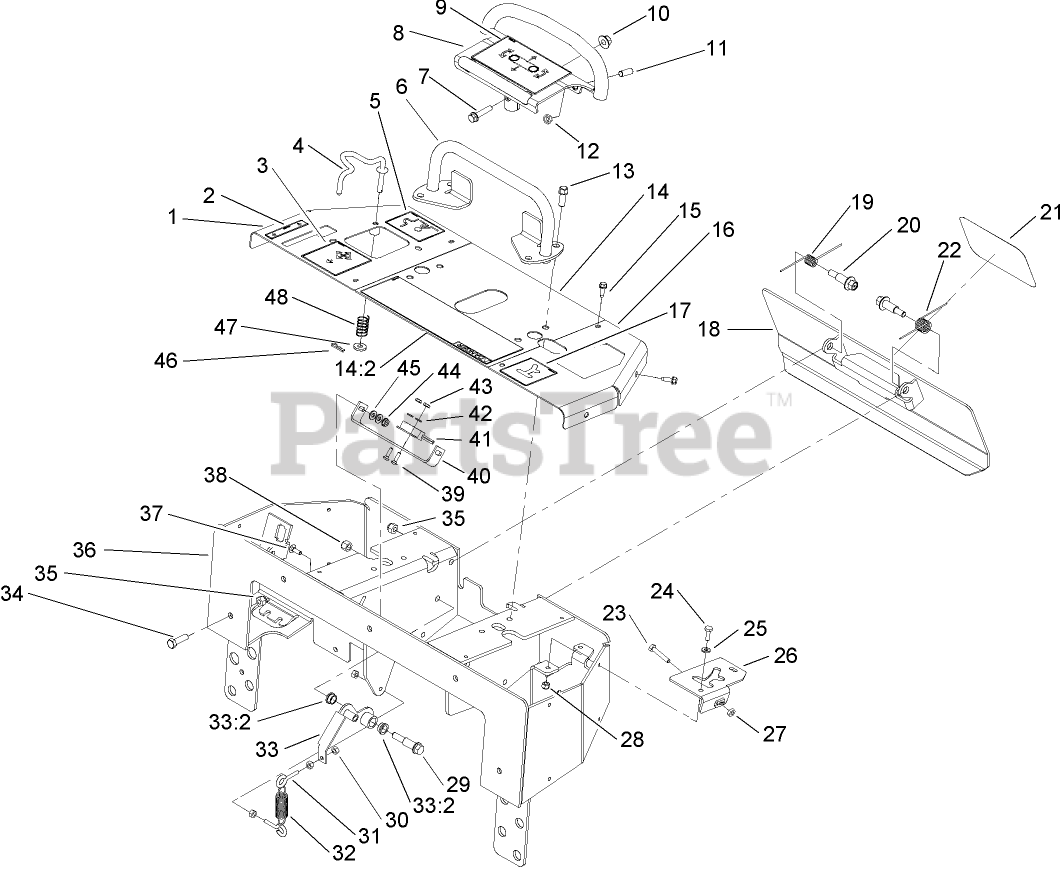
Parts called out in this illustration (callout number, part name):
1	RH PANEL ASM
2	DECAL-BRAKE
3	DECAL-LOADER
4	ROD-INTERLOCK
5	DECAL-INTERLOCK
6	REFERENCE BAR ASM
7	SCREW-HHF
8	CONTROL HANDLE ASM
9	DECAL-TRACTION
10	NUT-FLANGE
11	SCREW-SET
12	NUT-JAM
13	SCREW-TAPTITE
14	CENTER PANEL ASM
14:2	DECAL-DANGER
15	SCREW-HWH, THREAD ROLL
16	PANEL-LH
17	DECAL-AUXILARY
18	REVERSE PLATE ASM
19	SPRING-TORSION, LH
20	BOLT-SHOULDER
22	SPRING-TORSION, RH
23	SCREW-HH
24	SCREW-HH
25	WASHER-FLAT
26	AUXILIARY STOP ASM
27	NUT-JAM
28	NUT-LOCK, NI
29	BOLT-SHOULDER
30	NUT-HEX
31	BOLT-EYE
32	SPRING-EXTENSION
33	NEUTRAL CENTERING LEVER ASM
33:2	BUSHING-FLANGE
34	SCREW-HH
35	NUT-LOCK, NI
36	CONTROL PANEL ASM
37	BOLT-CARR
38	NUT-LOCK
39	SCREW-CARR
40	PLATE-SWITCH
41	SWITCH-PROXIMITY
42	WASHER-FLAT
43	NUT-KEPS
44	NUT-KEPS
45	WASHER-FLAT
46	PIN-COTTER
47	WASHER-FLAT
48	SPRING-CONTROL
